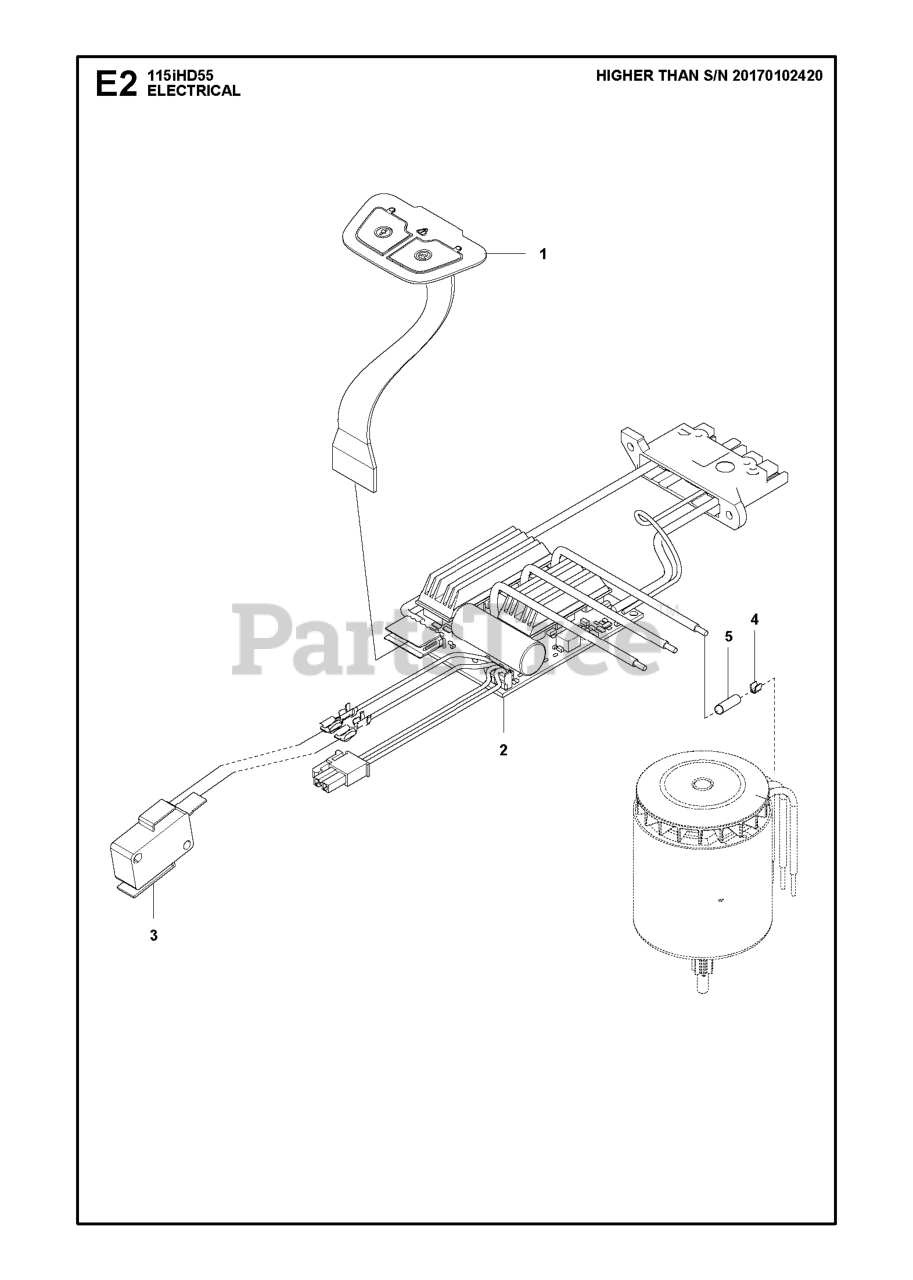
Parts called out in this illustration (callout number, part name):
1	KEYPAD HEDGE TRIMMER
2	CONTROL UNIT CONTROL UNIT BLDC
3	MICRO SWITCH
